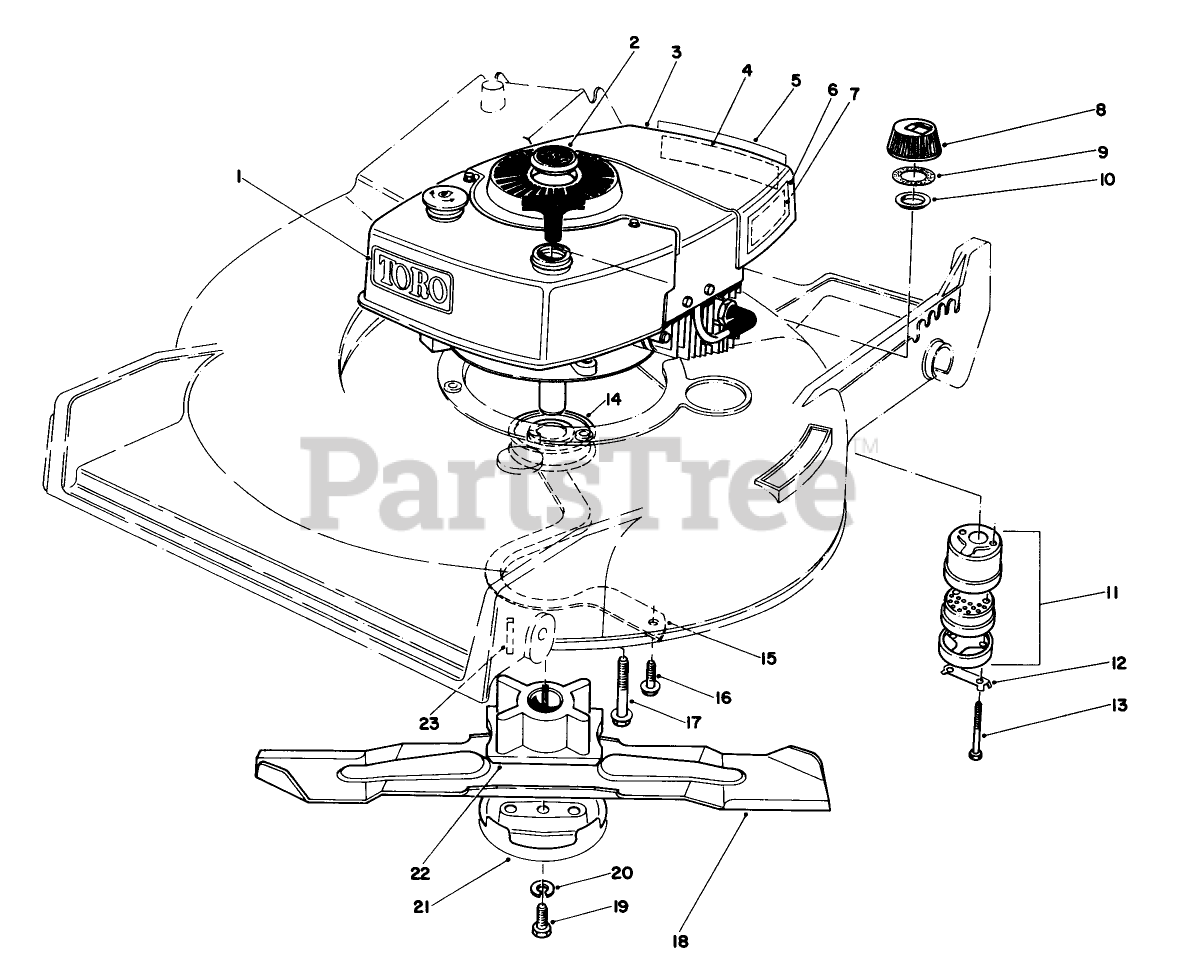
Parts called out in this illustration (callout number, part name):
3	Engine
9	GASKET
11	MUFFLER ASM
12	CLIP - LOCKING
13	SCREW-HH
17	3/8-16 X 2 CAPSCREW
19	SCREW-BLADE
20	WASHER-LOCK
22	BLADE RETAINER(DEEP)
23	KEY-SQUARE
